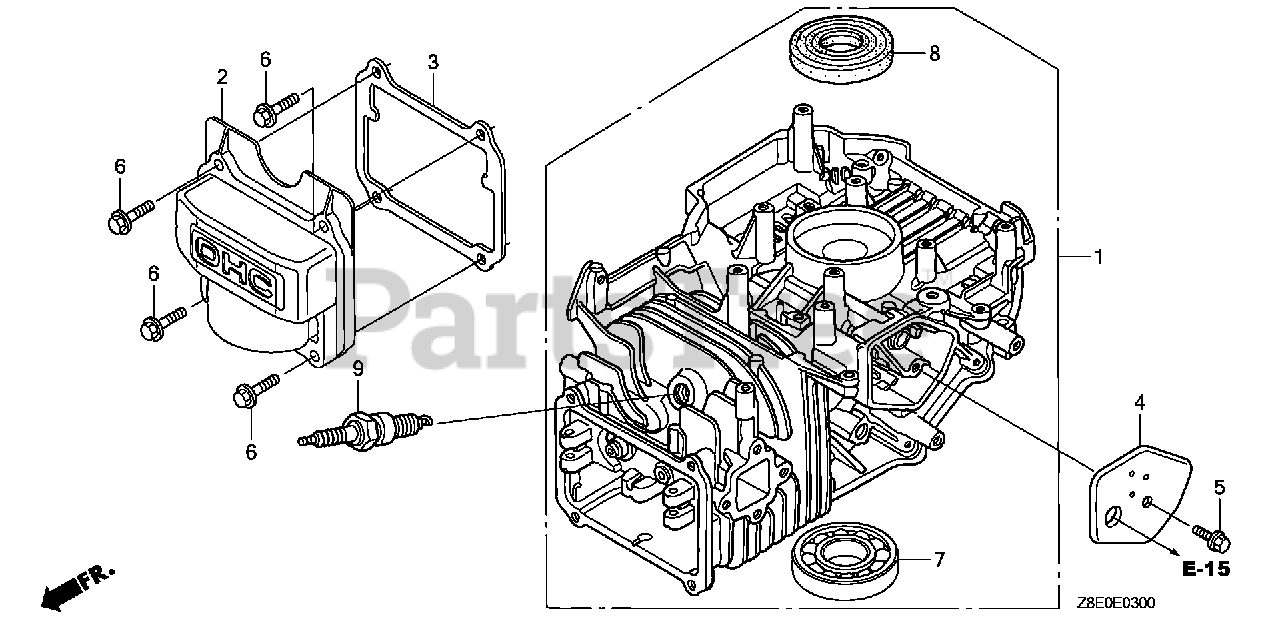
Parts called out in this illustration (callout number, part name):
1	CYLINDER ASSY.
2	COVER, CYLINDER HEAD
3	GASKET, HEAD COVER
4	COVER, BREATHER (BREATHER VALVE ASSY.)
5	BOLT, FLANGE (6X14) (CT200)
6	BOLT, FLANGE (6X25) (CT200)
7	BEARING, RADIAL BALL
8	OIL SEAL (25.4X74X6)
9	SPARK PLUG (BPR6ES) (NGK)
